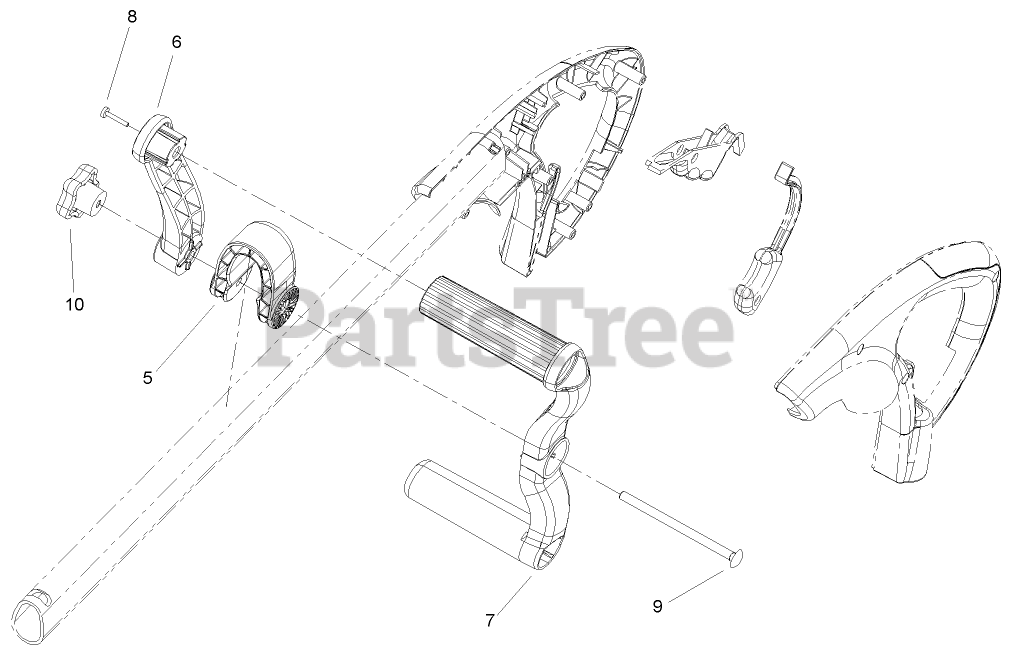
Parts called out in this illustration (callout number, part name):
5	COLLAR-HANDLE, ASSIST
6	HANDLE-ASSIST, RIGHT
7	HANDLE-ASSIST, LEFT
7	ASSIST HANDLE ASM
8	SCREW-PPH
9	SCREW-CARRIAGE
10	KNOB-HANDLE
